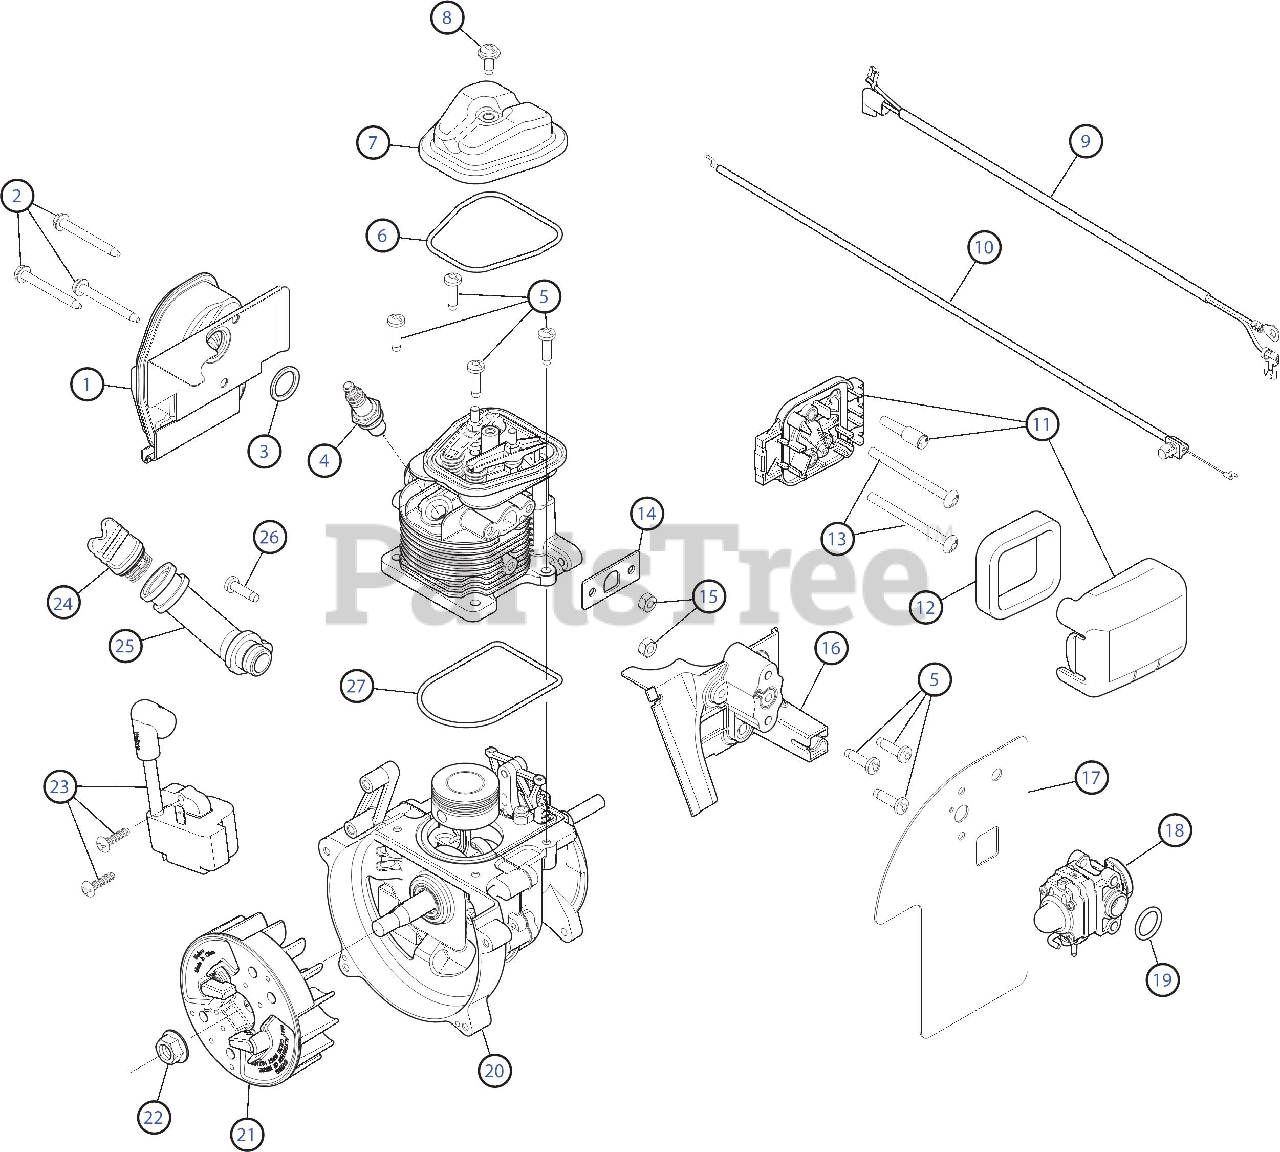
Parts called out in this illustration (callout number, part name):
1	Muffler Assembly
2	Muffler Screws
3	Muffler Gasket
4	Spark Plug
5	Screw
6	O-Ring
7	Rocker Cover
9	Lead Wire
10	Throttle Cable
11	Air Cleaner Assembly
12	Air Filter
14	Insulator Gasket
16	Insulator
17	Carburetor Gasket
18	Carburetor
19	Carburetor O-Ring
20	Short Block Assembly
21	Flywheel Asssembly
23	Module Assembly
24	Oil Plug
25	Oil Fill Tube
27	O-Ring
